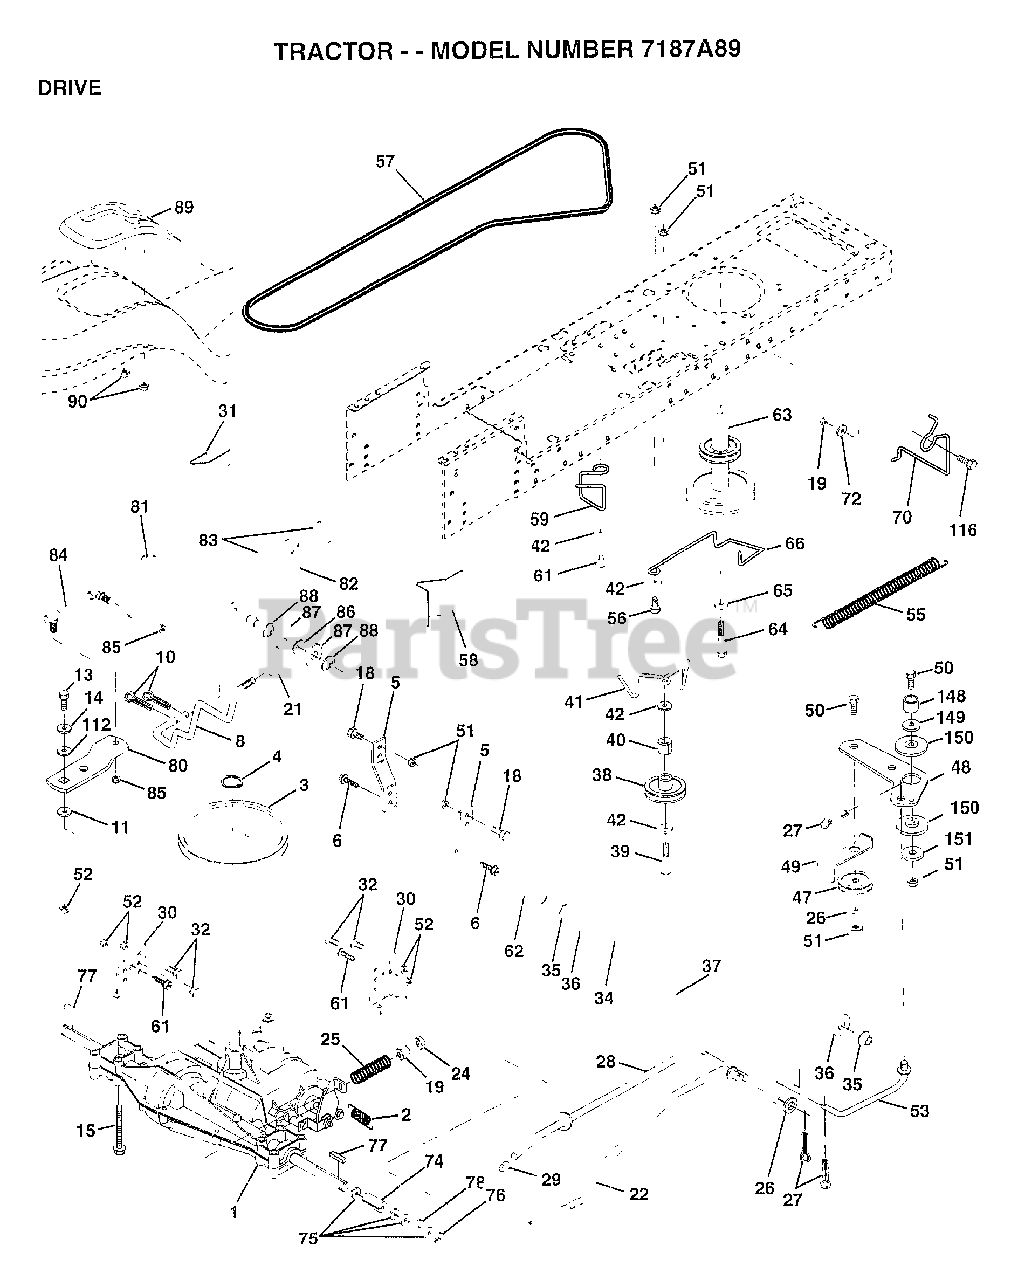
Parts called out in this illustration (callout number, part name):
2	SPRING.BRAKE.RETU
3	PULLEY TRANS
5	STRAP TORQUE
6	SCREW
8	"ROD SHIFT,FENDER"
10	PIN COTTER 1/8
11	WASH-SHFT PLT LT
13	BOLT.1/4-28.W/PAT
14	LOCKWASHER
15	BOLT.HX.FLG.5/16
18	BOLT FIN HEX 3/8-16 UNC X 1. GR 5
19	NUT
21	KNOB T (1/2-HOLE)
22	BRAKE ROD
24	NUT
25	SPRING ROD LT
26	WASHER
27	COTTER PIN
28	ROD.BRAKE.PARK.LT
30	TRANSAXLE MTG BKT
31	"KEEPER,BELT LH T"
32	BOLT
34	SHAFT ASM-PEDAL F
35	NYLON BEARING
36	WASHER LT
38	PULLEY.IDLER.FLAT
39	BOLT
40	SPACER T
42	WASHER
48	BELLCRANK.CLUTCH
49	RETAIN BELT
53	"LINK, CLUTCH T"
55	"SPRING, RETURN LT"
57	"V-BELT,95.3"
58	"KEEPER,BELT RH T"
59	KEEPER BELT CNTSP
61	SCREW
62	PEDAL COVER T
63	PULLEY.ENGINE
64	BOLT
65	LOCKWASHER
66	KEEPER-BELT
70	KEEPER BELT ENG
72	WASHER
74	SPACER LT
75	WASHER
76	E-RING LT
77	SQUARE KEY
78	WASHER
80	ARM.SHIFT.TRANS.
81	SHAFT ASSY CROSS
82	"SPRING,TORSION"
83	WASHER
84	"ROD.TIE.20""P930LT"
85	NUT.CNT.LOCK.1/4
86	BUSHING
87	WASHER D
88	KLIP RING
90	NUT
112	WASHER LT
116	BOLT RDHD 3/8-16
149	SPACER RETAINER
150	BUSHING.NYLON
151	WASHER
